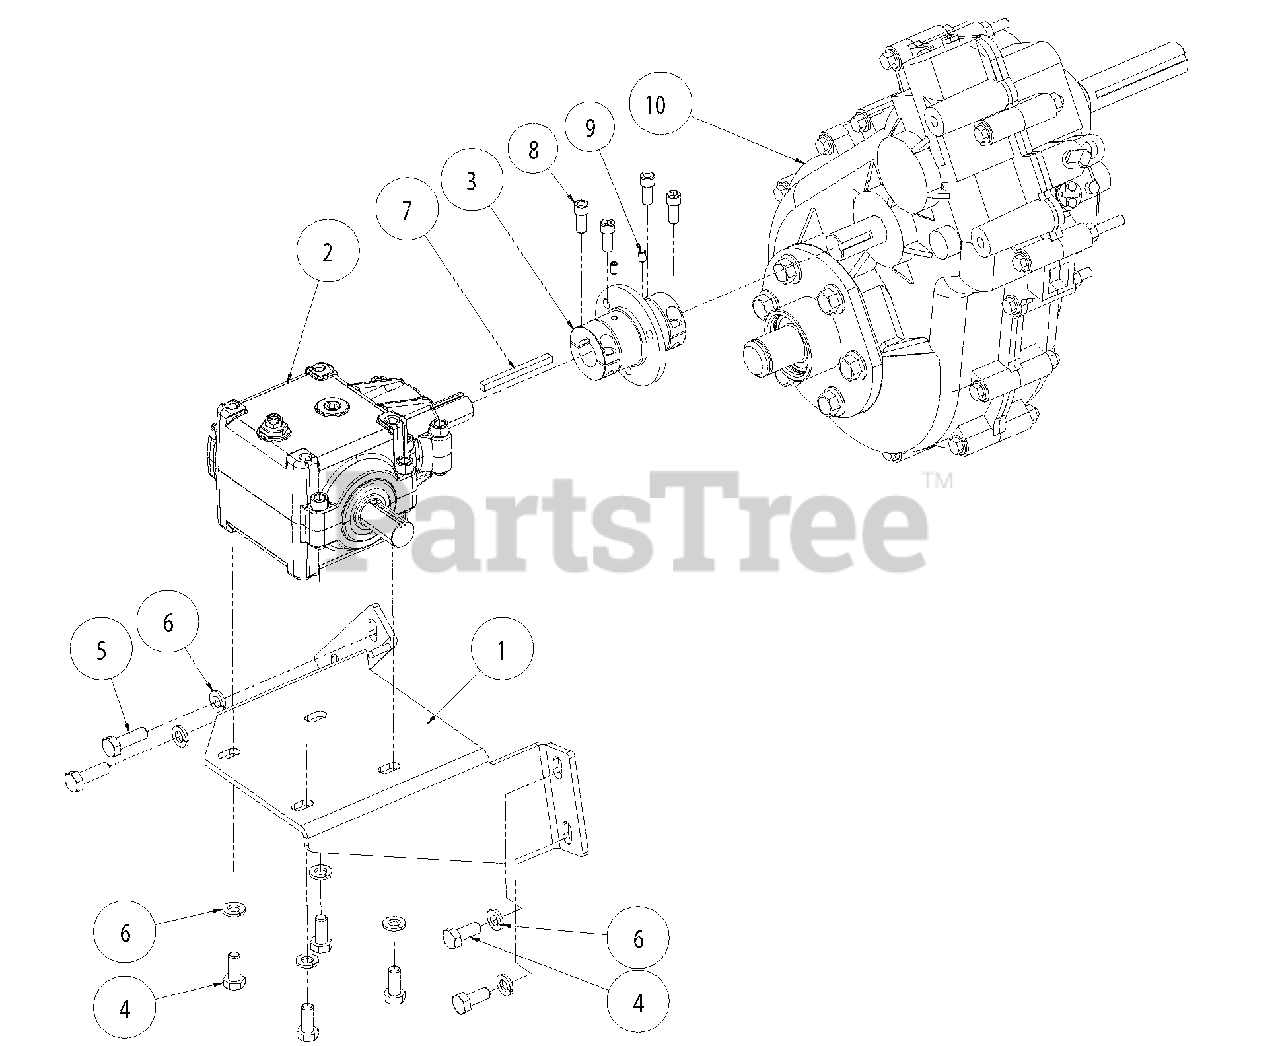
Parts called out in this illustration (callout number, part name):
1	GEAR BOX MNT PLATE
2	GBOX MODEL R100 1.5 TO 1 RATIO
3	CLAMP COUPLING
4	@BLT-HEX .31-18 .75 G5 YWZC
5	@BLT-HEX .31-18 1.00 G5 YWZC
6	WASHER, HELICAL SPRING LOCK, R
7	KEY .188 X .188 X 2.25 SQ
8	1/4-28 X 5/8
9	SET SCREW, 1/4-28 X 3/8 ALHD CUP
10	TRANSAXLE W/ AUTO-LOCK DIFF
